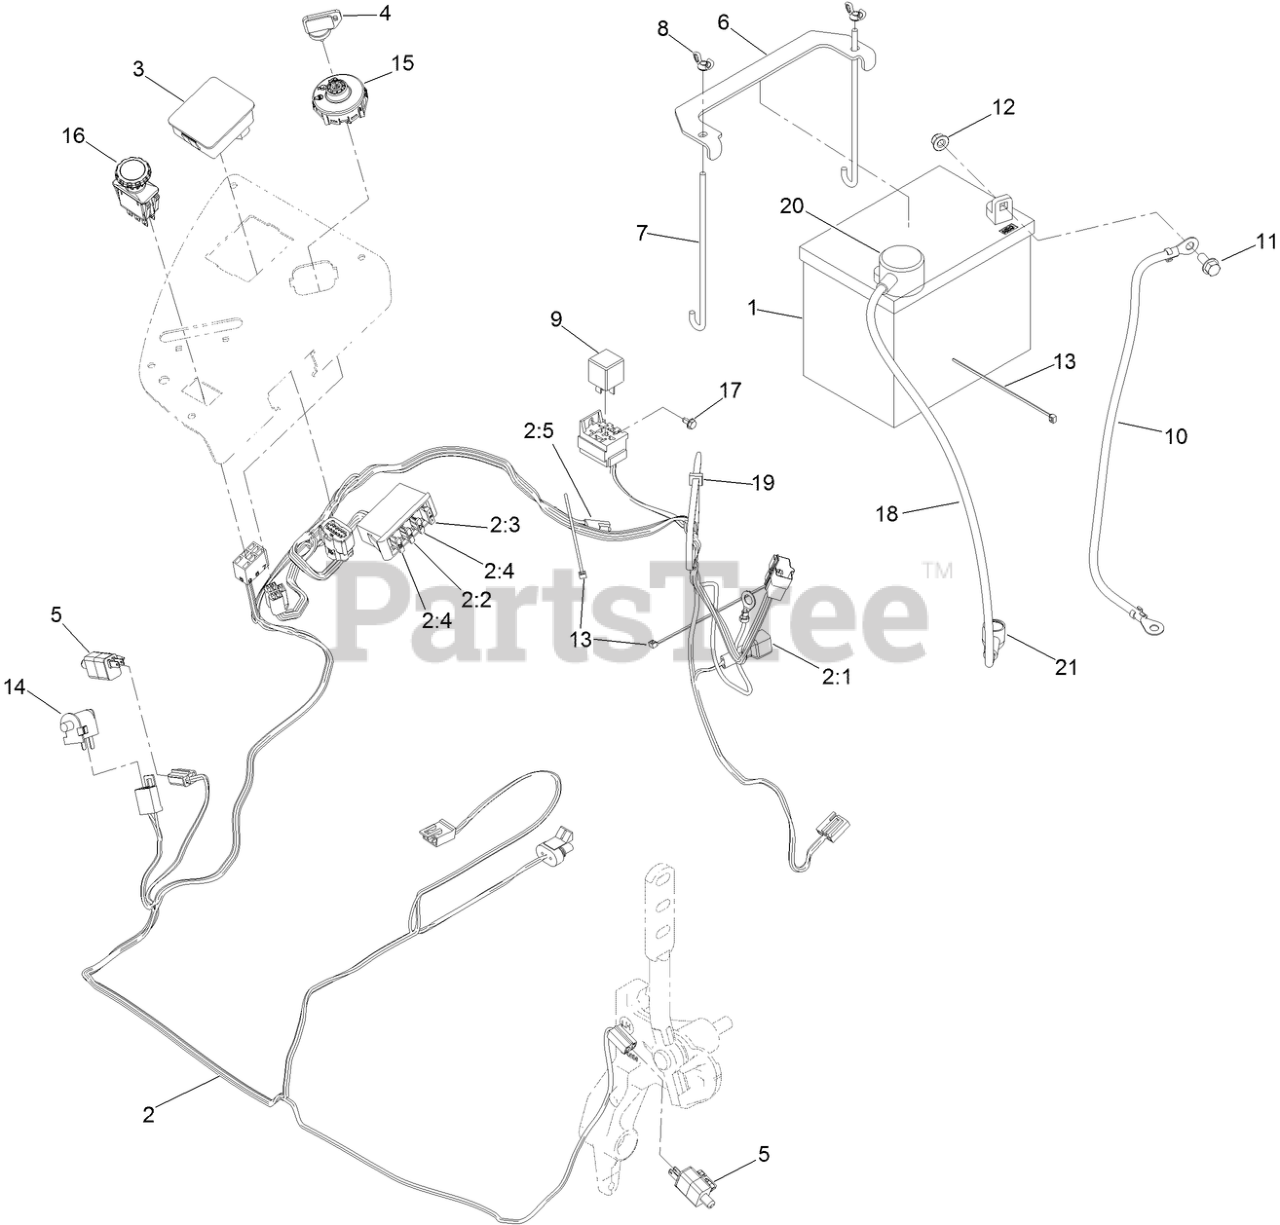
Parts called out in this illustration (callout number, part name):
1	BATTERY-DRY
2	HARNESS-WIRE, MAIN
2:2	FUSE-BLADE, 10 AMP
2:3	FUSE-BLADE, 15 AMP
2:4	FUSE-BLADE, 25 AMP
2:5	CAP-PLUG
3	FUEL/HOUR METER ASM
4	KEYS-IGNITION (SPARE PAIR)
4	KEY-IGNITION
5	SWITCH
6	STRAP-TIE DOWN, BATTERY
7	BOLT-HOLDDOWN
8	WINGNUT
10	CABLE-BATTERY, NEGATIVE
11	SCREW-HHF
12	NUT-HF, NI
13	TIE-CABLE
14	SWITCH-BAIL
15	SWITCH-IGNITION
16	SWITCH-PTO, 10 AMP
17	SCREW-HWH
18	CABLE-BATTERY, POSITIVE
19	TIE-CABLE
20	INSULATOR-BATTERY
21	INSULATOR-SOLENOID
